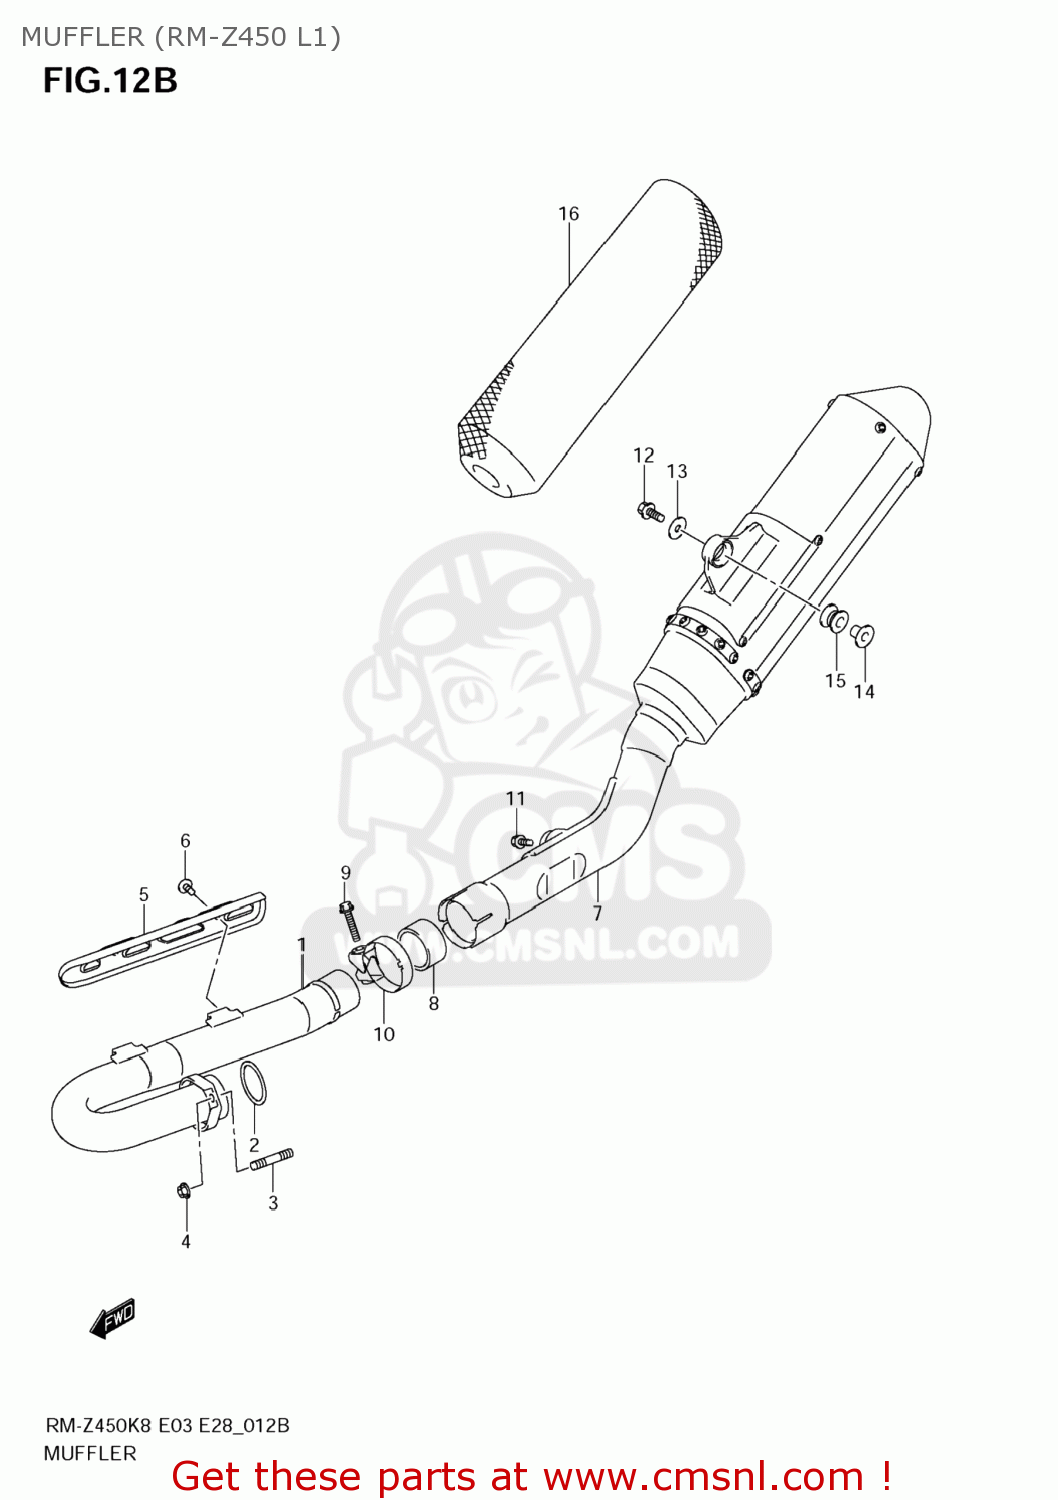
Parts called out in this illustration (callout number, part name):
1	PIPE,EXHAUST
2	GASKET,EXHAUST PIPE (NAS)
3	BOLT,STUD
4	NUT
5	COVER,EXHAUST PIPE
6	BOLT(6X8)
7	BODY,MUFFLER
8	CONNECTOR,MUFFLER
9	BOLT(8X35)
10	CLAMP,CONNECTOR
11	BOLT(8X20)
12	BOLT(8X35)
13	WASHER(8.5X26X1.6)
14	SPACER(8.6X12X18.5)
15	CUSHION
16	SILENCER,MUFFLER
